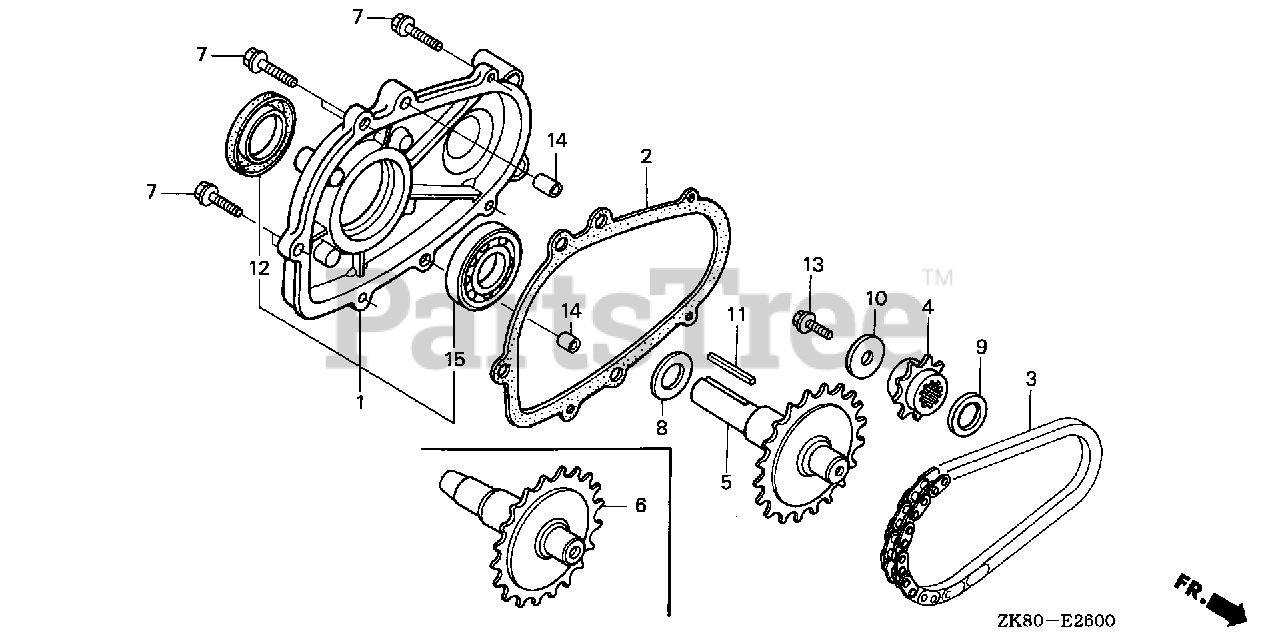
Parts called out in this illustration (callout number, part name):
1	COVER ASSY., CHAIN CASE
2	GASKET, CHAIN CASE COVER
3	CHAIN, P.T.O. DRIVE (DID317FM2-34LE)
4	SPROCKET, DRIVE (13T)
5	SHAFT, P.T.O. (26T)
7	BOLT, FLANGE (6X28) (CT200)
8	SPRING, THRUST
9	SPACER (20MM)
10	WASHER (8MM)
11	KEY (5X5X33) (YELLOW)
12	OIL SEAL (25X41X6)
13	BOLT, HEX. (8X25)
14	PIN, DOWEL (8X14)
15	BEARING, RADIAL BALL (6205)
